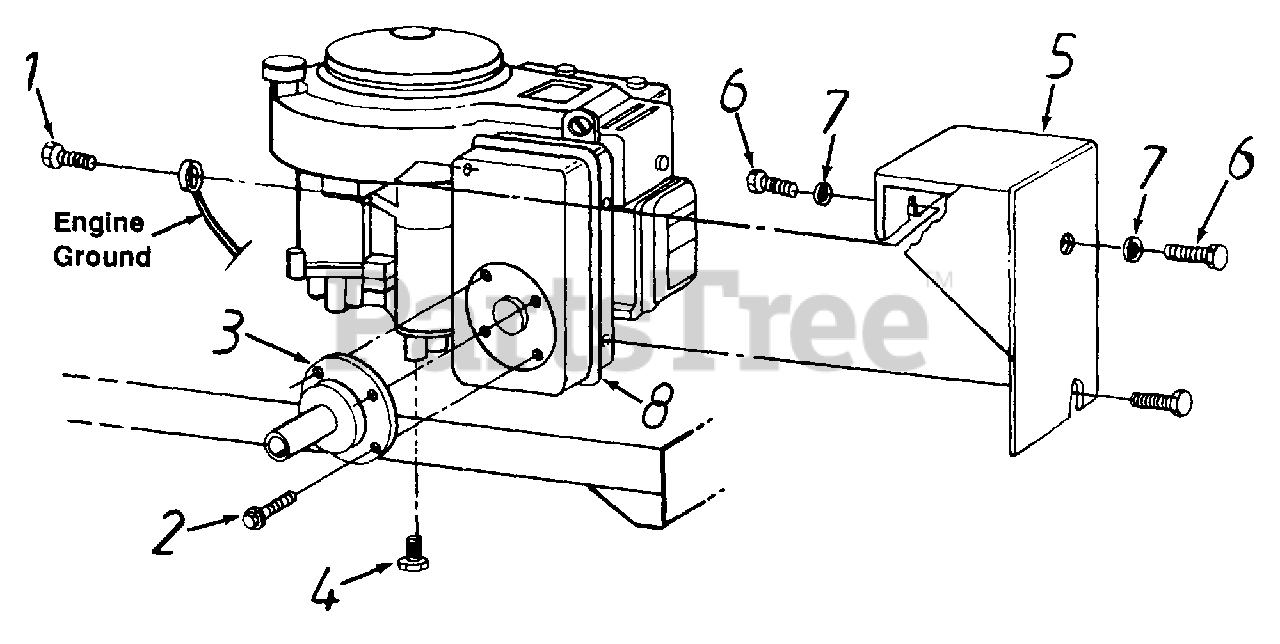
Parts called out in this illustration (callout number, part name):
1	Hex Bolt M6-1" x 10 MM Lg. (Gr. 5)
2	Hex Wash. Hd. F-Tap Scr. #3-32 x .38" Lg.
3	Exhaust Pipe Ass'y.
4	Hex L-Wash. TT-Tap Scr. 3/8-16 x 1" Lg.
5	Muffler Heat Shield Ass'y.
6	Hex Cap Scr. M6-1" x 14 MM Lg.
7	Bell-Wash..265" I.D. x .75" O.D.
8	Muffler - Supplied by Engine Manufacturer
